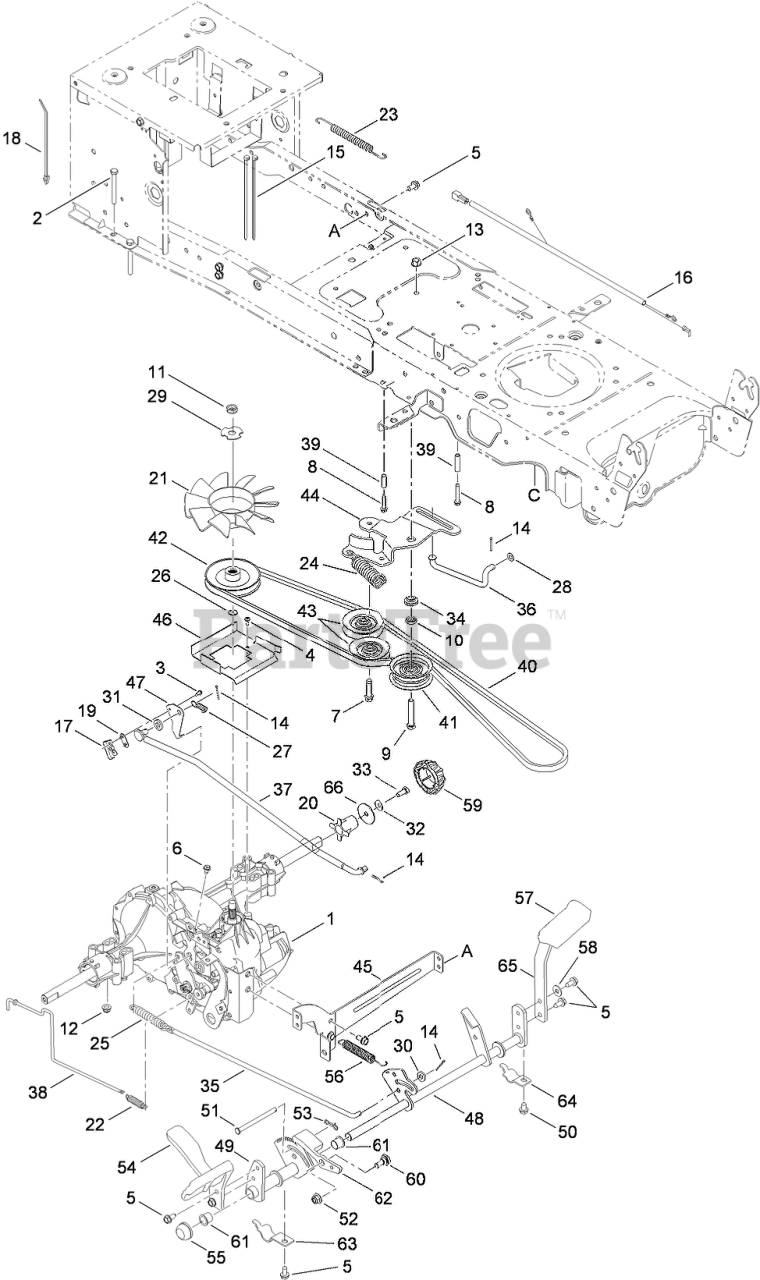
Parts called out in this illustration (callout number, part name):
1	HYDRO TRANSMISSION ASM
2	SCREW-HEX
3	SCREW-HWHTF
5	SCREW-TAP
6	SCREW-TAP
7	SCREW-TAP
8	SCREW-TAP
9	SCREW-HH
10	NUT-JAM
11	NUT-JAM
12	NUT-LOCK, FLANGE
13	NUT-LOCK, FLANGE
14	PIN-COTTER
15	TIE-CABLE
16	HARNESS-JUMPER
17	SWITCH-SPRING, SHORT
18	TIE-CABLE
19	PLATE-INSULATOR
20	SLEEVE
22	SPRING-EXTENSION
23	SPRING-EXTENSION
24	SPRING-EXTENSION
25	SPRING-EXTENSION
26	RING-WIRE
27	SPRING-EXTENSION
28	WASHER-FLAT
29	WASHER-LOCK
30	WASHER-FLAT
31	WASHER-FLAT
32	WASHER-BELL
33	SCREW-HH
34	SPACER-SHOULDER
35	ROD-BRAKE
36	ROD-BYPASS, FOOT PEDAL
37	ROD-CONTROL
38	ROD-BYPASS, HYDRO
39	SPACER
40	BELT-V
41	PULLEY-IDLER, FLAT
42	PULLEY-INPUT
43	PULLEY-IDLER, Y TYPE
44	BRACKET-IDLER, CENTER DOUBLE
45	BRACKET-MOUNTING
46	BRACKET-SUPPORT, BELT DISENGAGE
47	BRACKET-ACTUATOR
48	BRAKE CONTROL ASM
49	BRACKET-PEDAL
50	SCREW-HWH
51	PIN-CLEVIS
52	NUT-LOCK, FLANGE
53	PIN-COTTER
54	PEDAL-CONTROL
55	CAP-PUSH
56	SPRING-EXTENSION
57	PAD-PEDAL, BRAKE
58	WASHER-BELL
59	CAP-HUB
60	BOLT-SHOULDER
61	BEARING-FLANGE
62	LATCH-CRUISE
63	BRACKET-STRAP, PEDAL SUPPORT
64	BRACKET-STRAP, PEDAL SUPPORT
65	BRACKET-PEDAL, BRAKE
66	WASHER-FLAT
